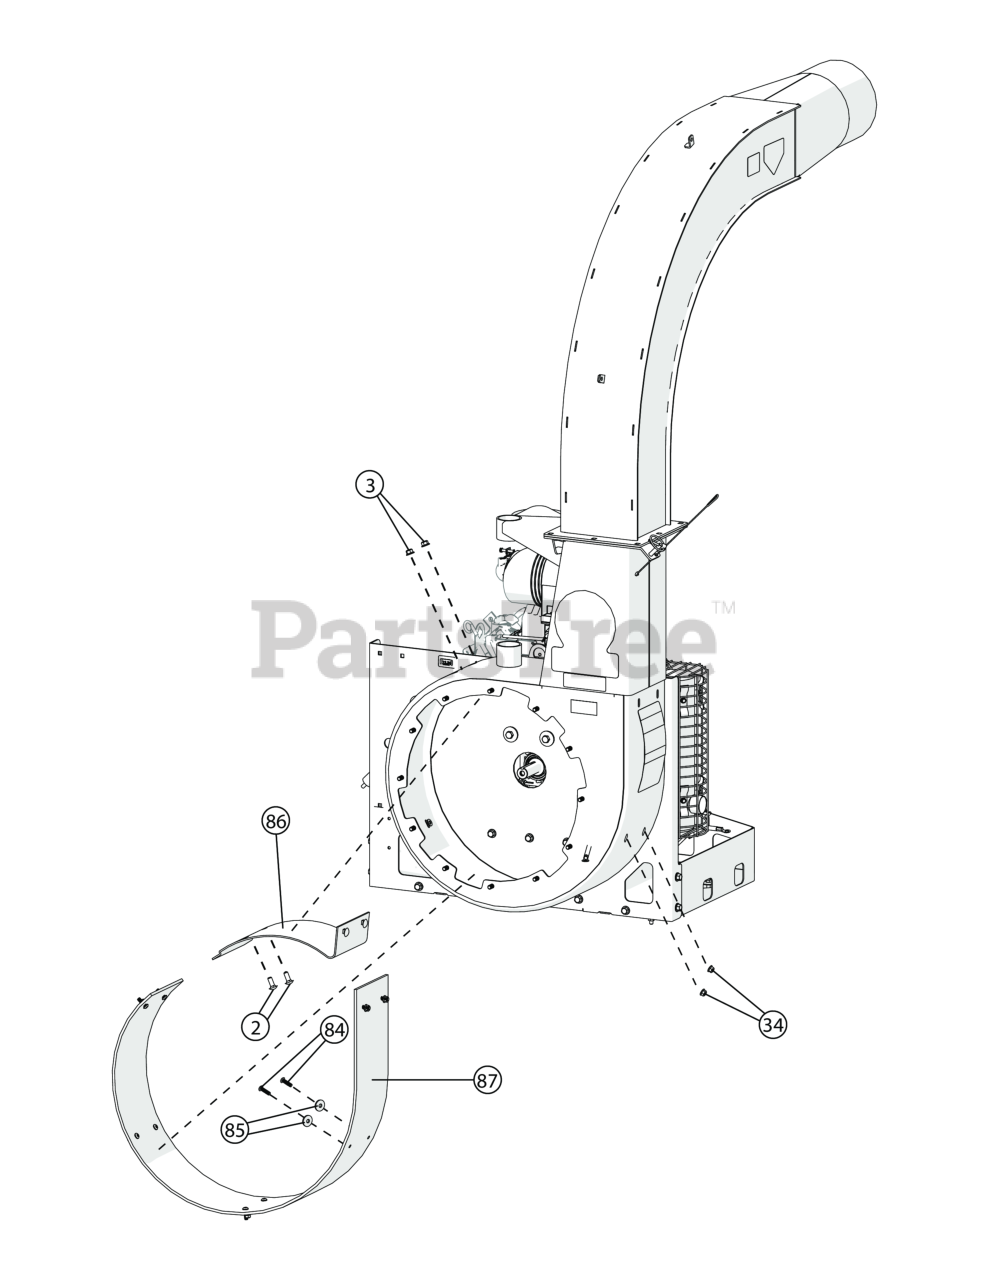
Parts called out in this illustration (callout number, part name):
2	BOLT CARRAIGE 3/8-16 X 1" ZP
3	NUT-HEX-NYLK, FLG .375"-16 ZP
34	NUT-HEX-NYLK, FLG .3125-18 ZP
84	SCREW BUTTON HEAD 5/16"-18 X 1.00
85	WASHER 5/16" SAE Z/P
86	CUT OFF REPLACEABLE DL
87	SEE: 791018-S
